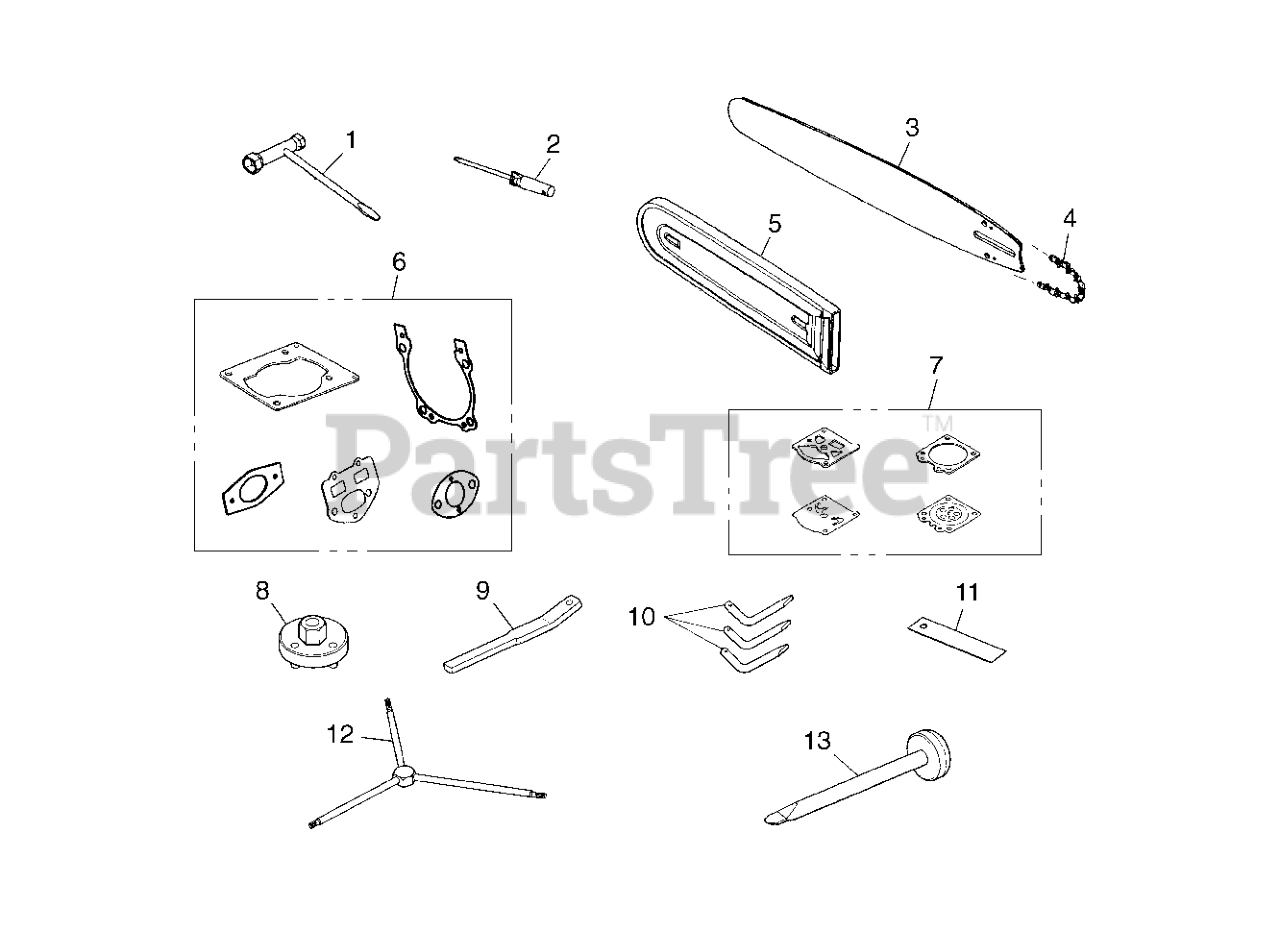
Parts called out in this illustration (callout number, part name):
3	BAR 16"(FITS:G3800 & GZ4000)
4	CHAIN (16") FOR G3800 GZ4000
6	GASKET KIT (ENG)
7	GND-27- G-KIT
